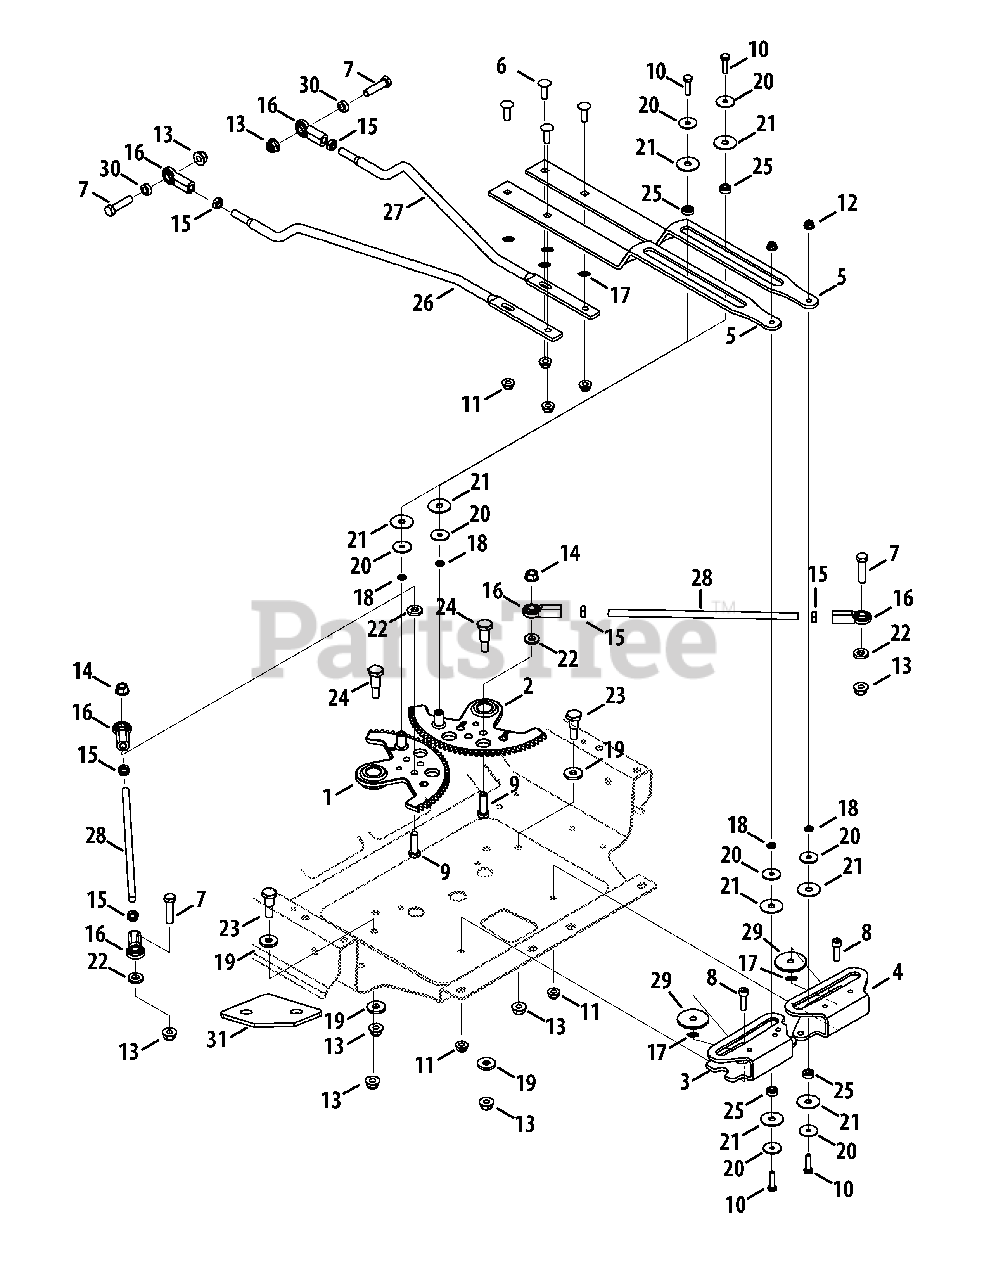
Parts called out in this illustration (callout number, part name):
1	Steering Gear Assembly, RH
2	Steering Gear Assembly, LH
3	Speed Cam Plate, RH
4	Speed Cam Plate, LH
5	Control Link
6	Carriage Screw, 5/16-18 x 1.00
7	Hex Screw, 3/8-16 x 1.50
9	Hex Screw, 3/8-16 x 1.25
10	Hex Screw, 1/4-20 x 1.00
11	Flange Lock Nut, 5/16-18
12	Flange Lock Nut, 1/4-20
13	Flange Lock Nut, 3/8-16
14	Flange Lock Nut, 3/8-16
15	Jam Nut, 3/8-24
16	Female Ball-Joint
17	Speed Nut,
18	Push Nut, .25 ID x .50 OD
19	Flat Washer, .385 x 1.00 x .135
20	Flat Washer, .255 x 1.00 x .060
21	Washer, .355 x 1.25 x .048
22	Flat Washer, .407 x .812 x .135
23	Shoulder Screw, 3/8-16 x .50 x .66
24	Shoulder Screw, 3/8-16 x .500 x .875
25	Ball Bearing, .25 x .625
26	Hydro Link, RH
27	Hydro Link, LH
28	Drag Link, .375 Dia.
29	Shoulder Spacer, .755 x .125
30	Spacer, .380 ID x .625 OD x .21
31	Steering Plate Support RH
31	Steering Plate Support LH
